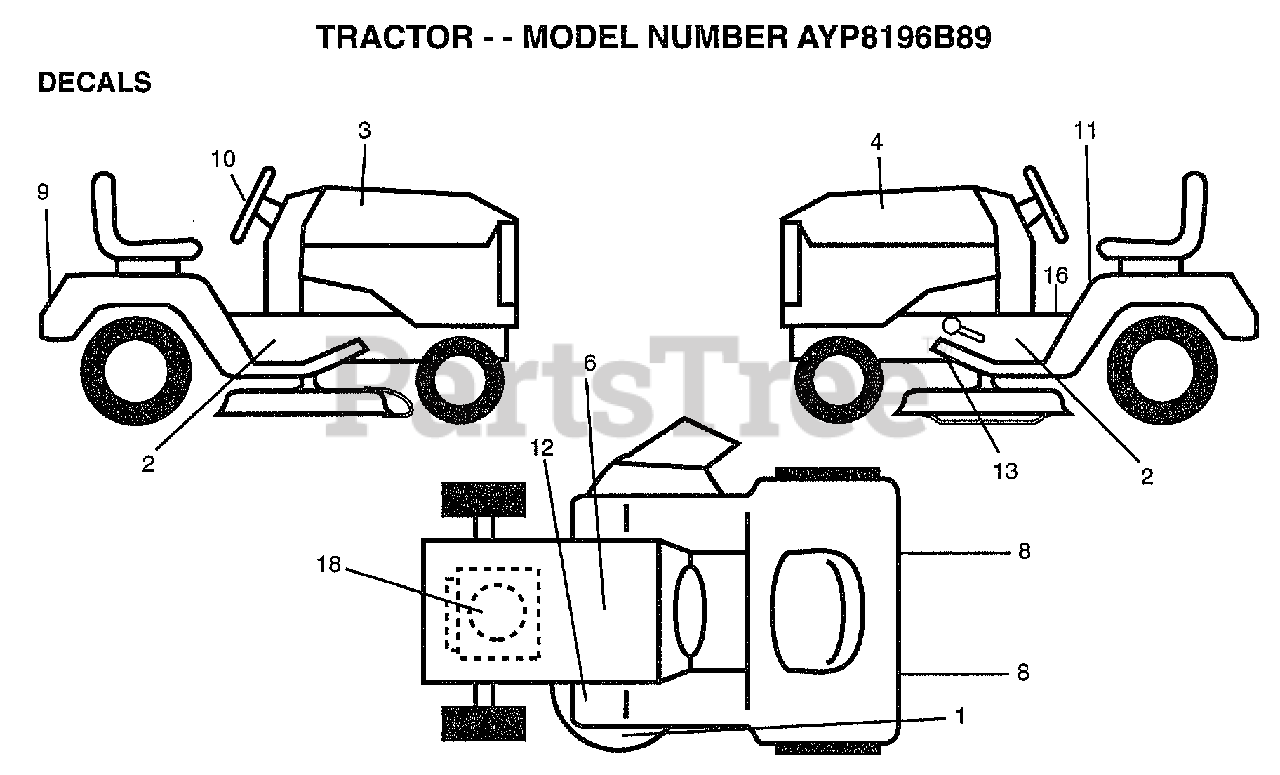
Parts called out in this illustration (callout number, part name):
1	DECAL DECK WIZ +
2	"DECAL CHASSIS 46"""
3	DECAL.HOOD.RH
4	DECAL.HOOD.LH
6	DECAL.BATRY.3-3908
8	REFLECTOR-TAIL YT
10	DECAL.INS.STRG.WL
11	"DECAL DANGER,FEND"
13	"DECAL.V.BELT.44"""
16	"DECAL DASH,OPER."
18	DECAL HP ENGINE
